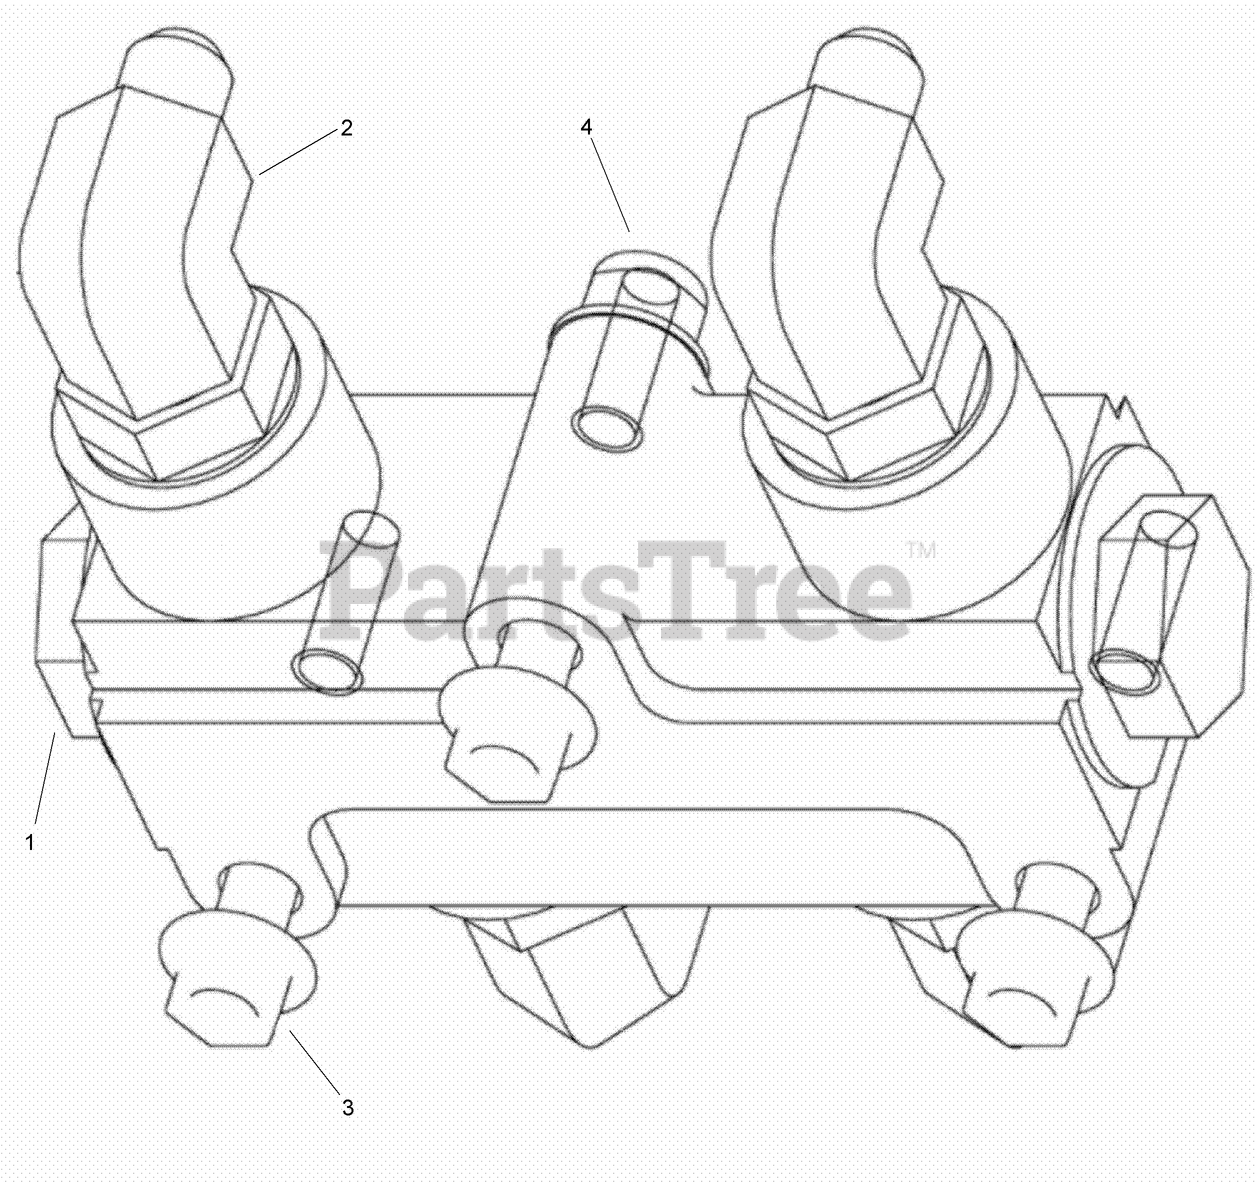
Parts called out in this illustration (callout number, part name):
1	HYD LOCKOUT VALVE ASM
2	ELBOW-90 Adj 37FL, 3/8 x 1/2 Tube
3	SCREW-FLANGE
4	NUT-TORQUE, PREVAILING
